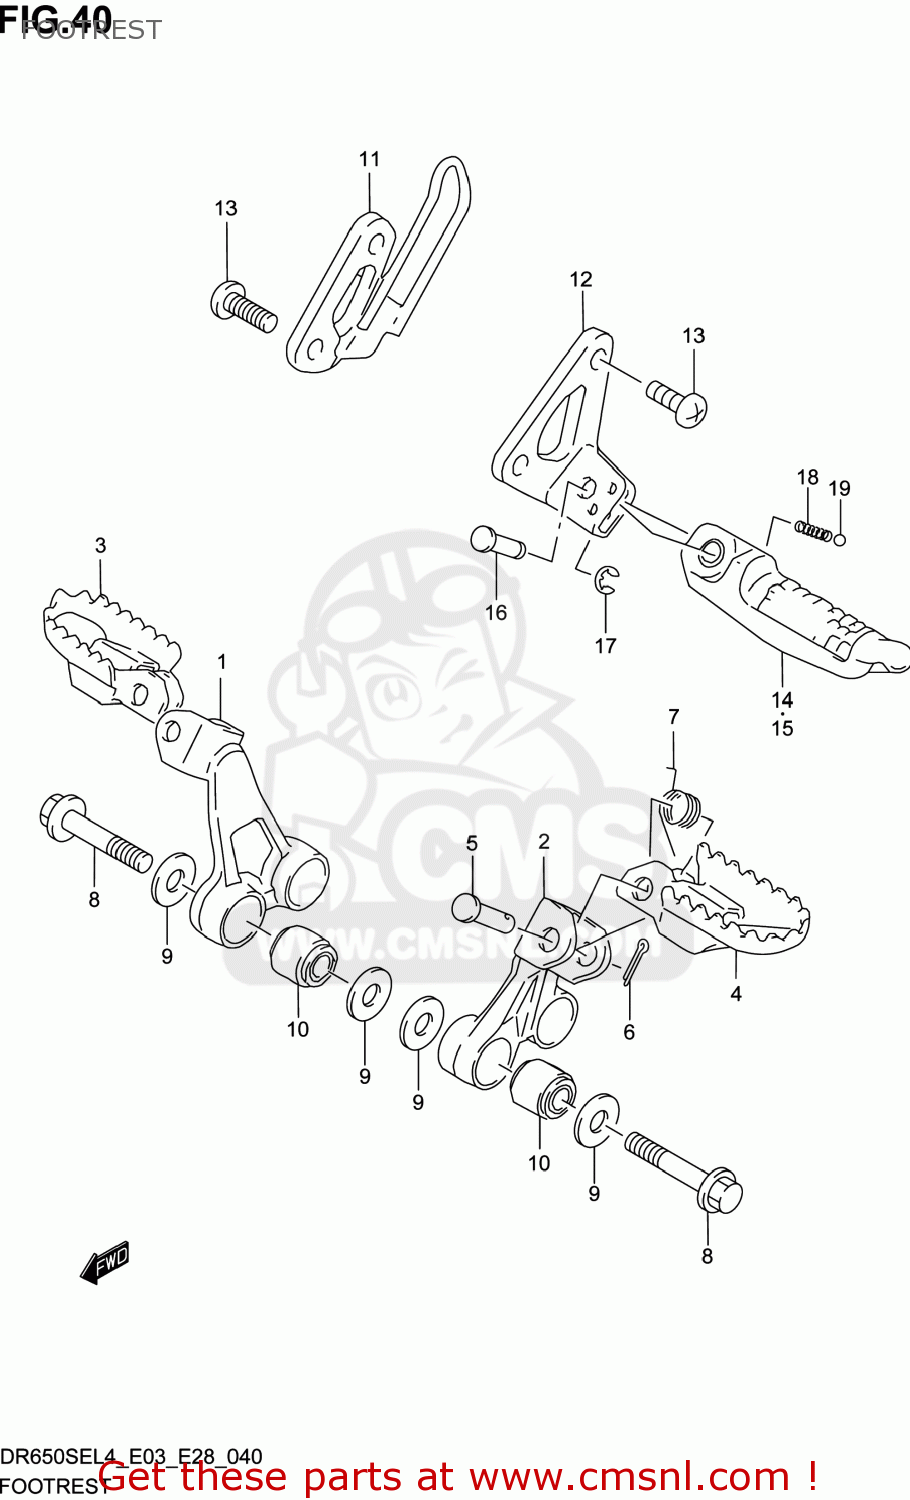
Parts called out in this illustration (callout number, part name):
1	BRACKET,FR FOOTREST,R
2	BRACKET,FR FOOTREST,L
3	FOOTREST,FR,R
4	FOOTREST,FR,L
5	PIN
6	PIN
7	SPRING
8	BOLT(10X50)
9	WASHER(10.1X23X2.3)
10	BUSH(10.2X25X19)
11	BRACKET,PILLION FOOT,R(BLACK)
12	BRACKET,PILLION FOOT,L(BLACK)
13	BOLT(8X20)
14	BAR,PILLION FOOTREST,R
15	BAR,PILLION FOOTREST,L
16	PIN
17	E RING
18	SPRING
19	BALL
